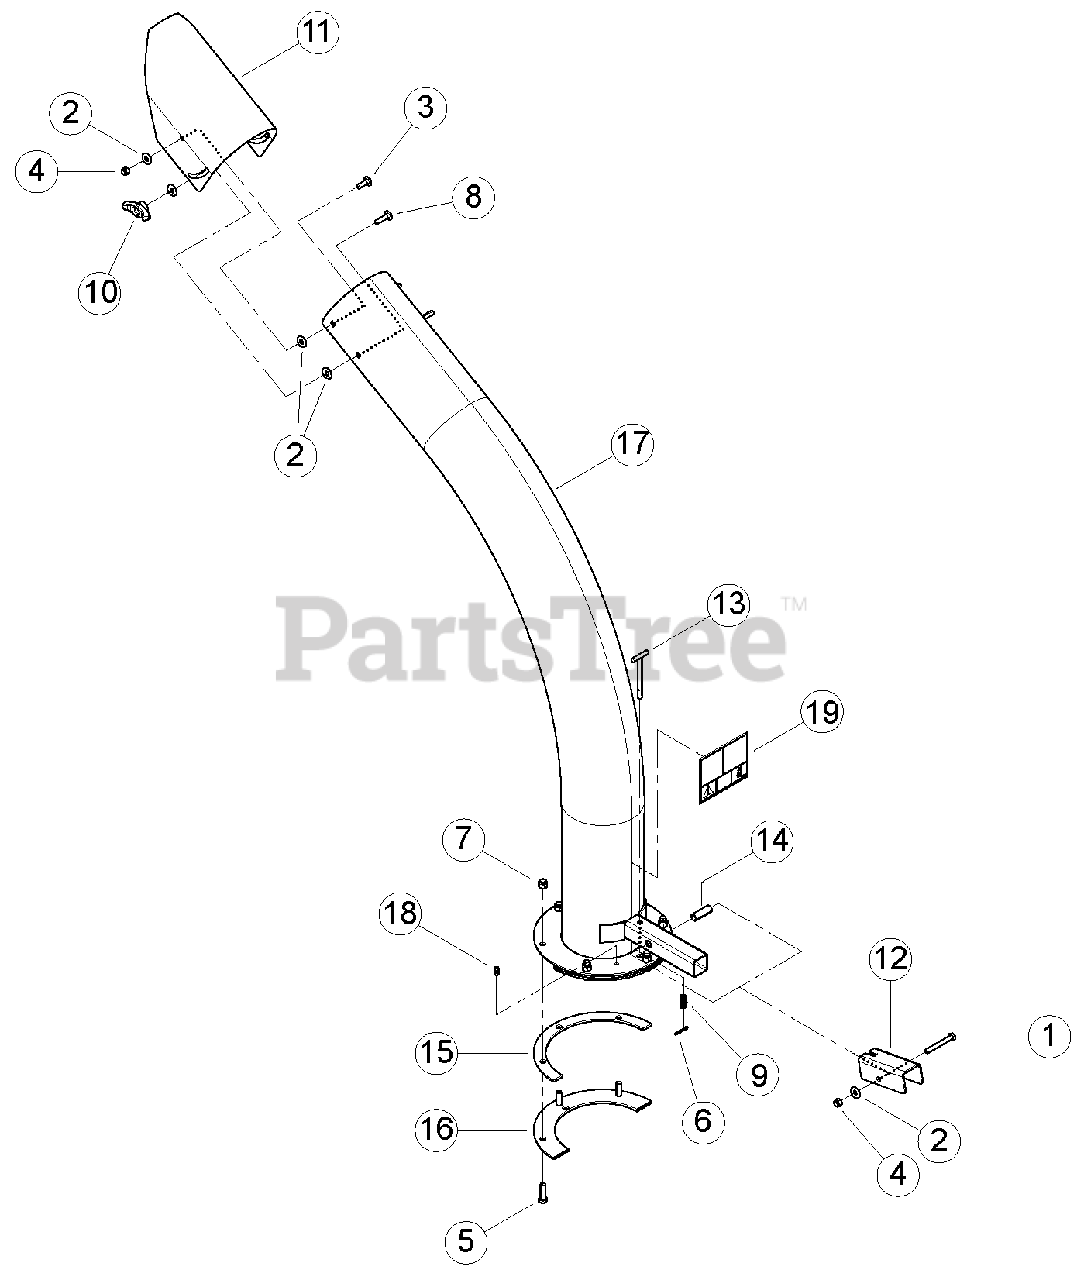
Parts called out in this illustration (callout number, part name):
1	BOLT, 5/16 X 2-1/2 HEX HD GR5 ZP
2	WASHER, 5/16 FLAT ZP
3	BOLT, 5/16 X 1 CRG GR5 ZP
4	NUT, 5/16 NE NYLOCK ZP
5	BOLT, 3/8 X 1-1/4 HEX HD GR5 ZP
6	PIN, 1/8 X 1.00 COTTER ZP
7	NUT, 3/8 NE NYLOCK ZP
8	BOLT, 5/16 X 1-1/4 CRG GR5 ZP
9	SPRING, LOCK COMPRESSION
10	KNOB, 5/16-18 UNC TEE W/LOCKING INSERT
11	DEFLECTOR, BLOWER-VAC DISCHARGE
12	LEVER, DISCHARGE LOCK
13	WELDMENT, DISCHARGE LOCK PIN
14	TUBE, DISCHARGE LOCK PIVOT
15	SPACER, DISCHARGE PIVOT
16	RING, DISCHARGE CLAMP
17	ASSEMBLY, 6 INCH DISCHARGE SERVICE PART
18	FITTING, 1/4 SELF-TAP GREASE
19	DECAL, DISCHARGE DEBRIS & LOCK
